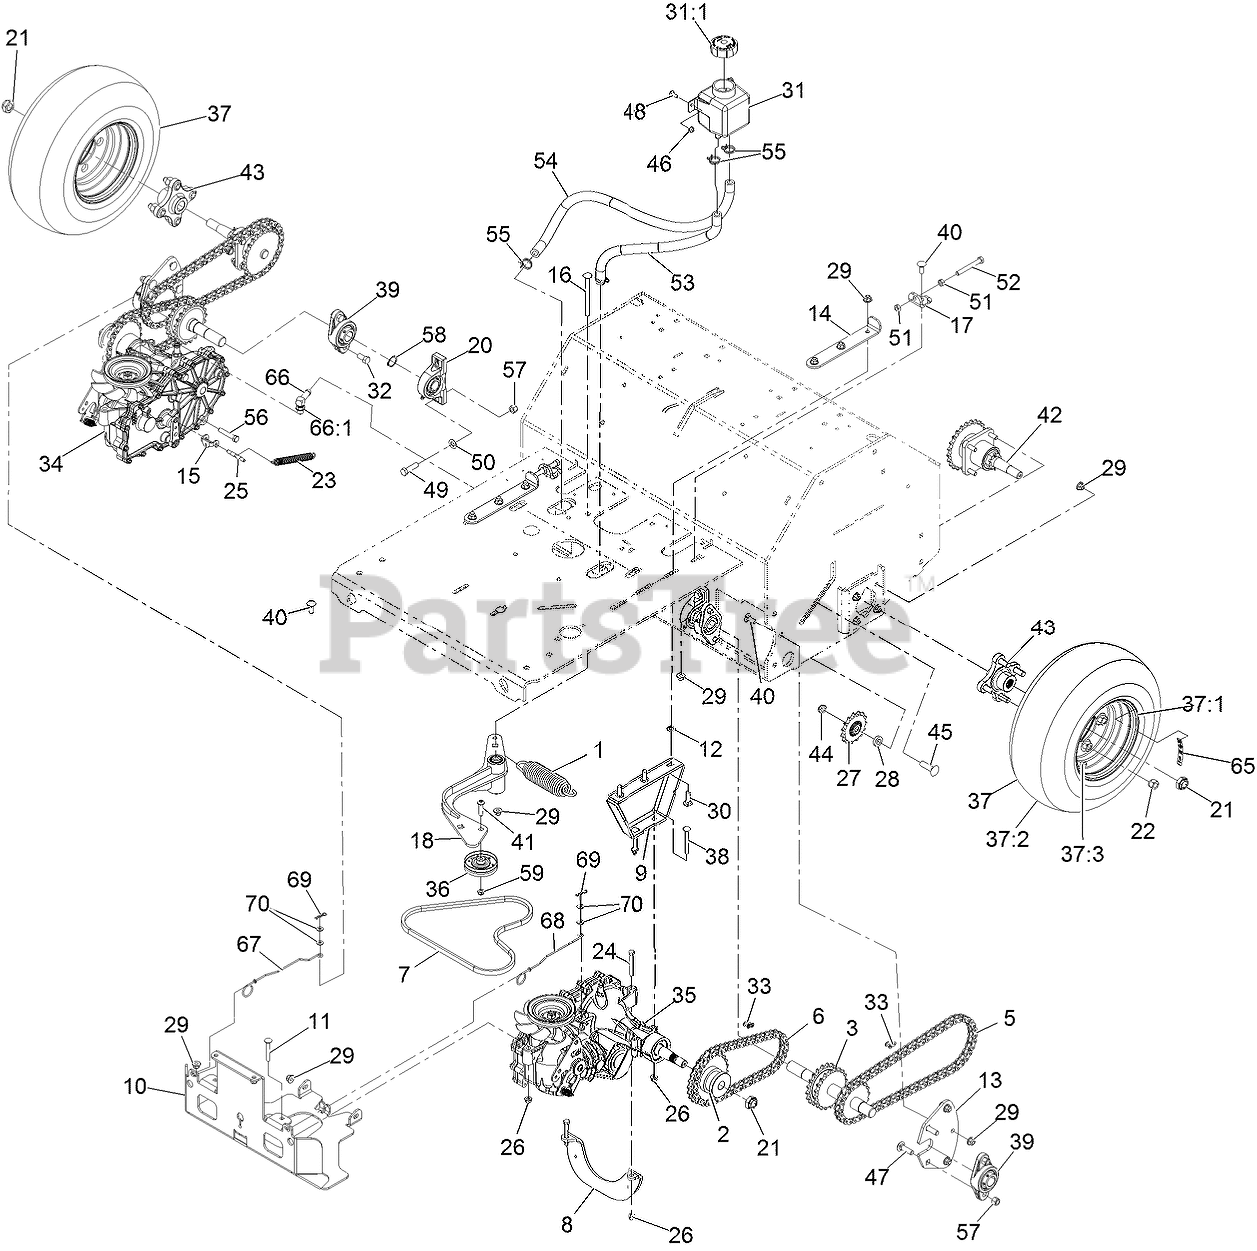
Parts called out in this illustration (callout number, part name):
1	SPRING-EXTENSION
2	HUB-DRIVE, CHAIN
3	JACKSHAFT
5	CHAIN-ROLLER
6	CHAIN-ROLLER
7	BELT-4L SECTION
8	Brace-Angle
9	MOUNT-TRANSMISSION
10	GUARD-TRANSMISSION
11	BOLT-CARR
12	NUT-PUSH
13	PLATE-JACKSHAFT
14	PLATE-ADJUSTMENT, TRANSMI
15	YOKE-BRAKE, PARK
16	BOLT-CARR
17	BRACKET-HYDRO, ADJUST
18	IDLER ARM ASM
20	BEARING-PILLOW BLOCK
21	NUT-LOCK
22	NUT-LUG
23	SPRING-DOOR
24	SCREW-HH
25	PIN-BRAKE, PARK
26	NUT-HF, NI
27	SPROCKET-IDLER, 15T
29	NUT-HF, NI
30	BOLT-CARR
31	TANK-HYD
31:1	CAP-RESERVOIR, HYD
32	SCREW-HH
33	LINK-CONNECTING
34	TRANSAXLE-ZT3100, RT (W/P
35	TRANSAXLE-ZT3100, LT (W/P
36	PULLEY-IDLER
37	TIRE ASM (16 X 6.50-8)
37:1	RIM (8 X 5.375)
37:3	Stem-Valve
38	SCREW-CARR
39	BEARING-FLANGE, 2 BOLT
40	BOLT-CARR
41	SCREW-HSBH
42	AXLE AND BEARING ASM
43	HUB-OFFSET
44	NUT-HEX
45	SCREW-CARR
47	BOLT-CARR
48	BOLT-CARR
50	WASHER-FLAT
51	NUT-HEX
52	SCREW-HH
53	HOSE-HYDRAULIC
54	HOSE-HYDRAULIC
55	CLAMP-HOSE
56	SCREW-HH
57	NUT-LOCK, NI
58	RING-RETAINING
65	DECAL-HUB, WHEEL
66	FITTING-ELBOW, 90
66:1	O-RING
67	ROD-BYPASS, RH
68	ROD-BYPASS, LH
69	PIN-COTTER
99	OIL-HYD, (QUART)
